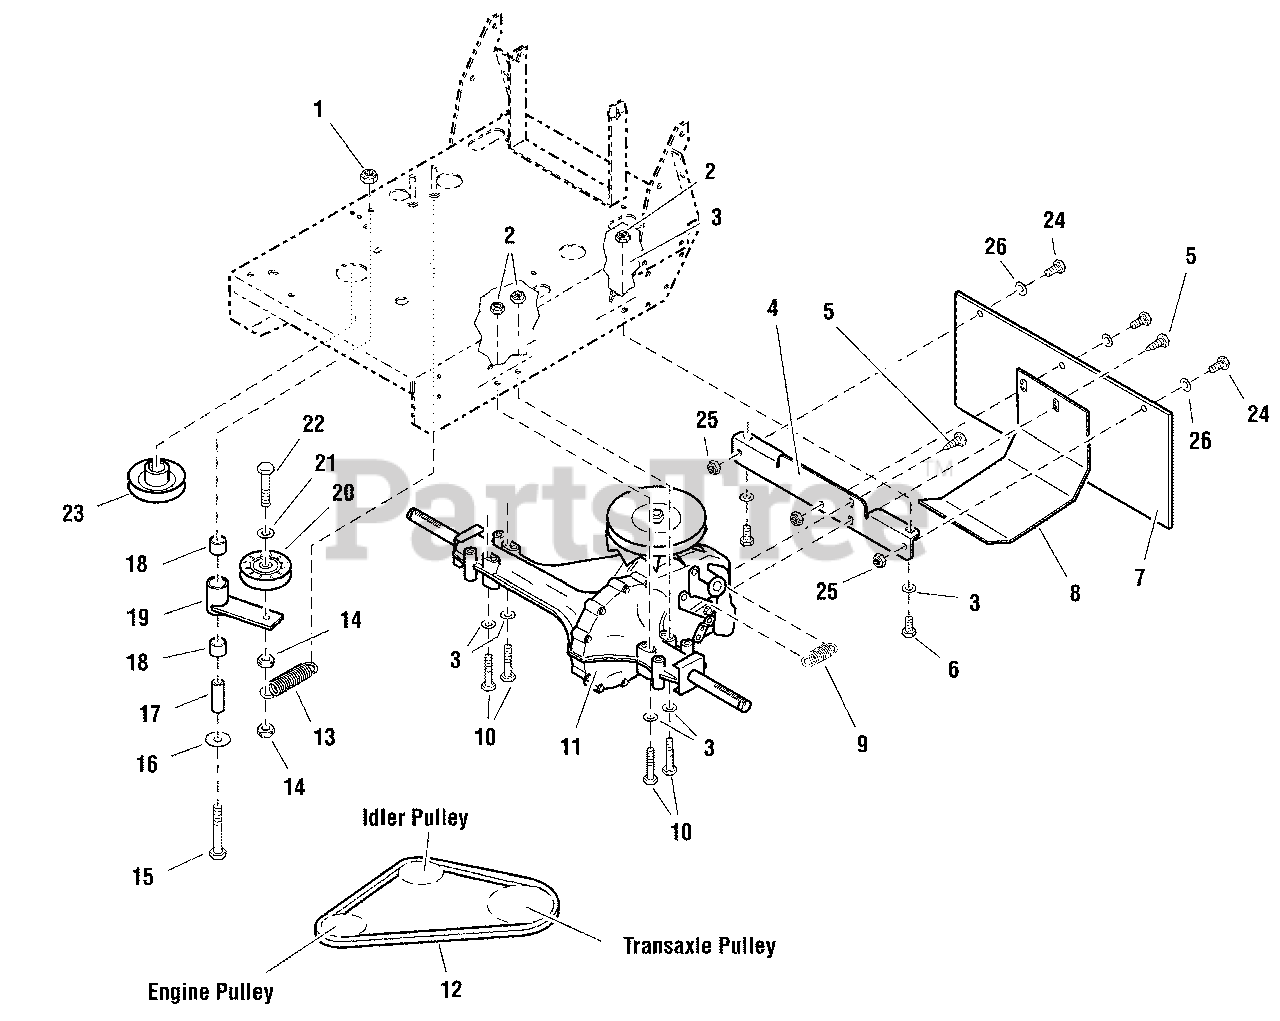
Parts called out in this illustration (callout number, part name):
1	NUT, Hex Nylon Lock, 3/8-16
2	NUT, Hex Nylon Lock, 5/16-18
3	WASHER, 5/16
4	TRANSAXLE BRACE
5	CAPSCREW, Hex Head, Self-Tapping, 5/16-18 x 3/4
6	CAPSCREW, Hex Head, 5/16-18 x 3/4
7	RUBBER FLAP
9	HYDRO RETURN SPRING
10	CAPSCREW, Hex Head, 5/16-18 x 3
11	TRANSAXLE, HYDROSTATIC
13	SPRING, Extension
14	NUT, Hex, Side Lock, 3/8-16
15	CAPSCREW, Hex Head, 3/8-16 x 3
16	WASHER, Fender, 3/8
17	SPACER
18	BUSHING, Brass
19	TRANSAXLE IDLER ARM
20	IDLER PULLEY ASSEMBLY
21	WASHER, 3/8
22	CAPSCREW, Hex Head, 3/8-16 x 2
23	TRANSAXLE DRIVE PULLEY
24	BOLT, 3/8 - 16 X 1
25	BOLT, 3/8 - 16, HEX NYLON FLANGE
26	WASHER, 3/8 SAE
